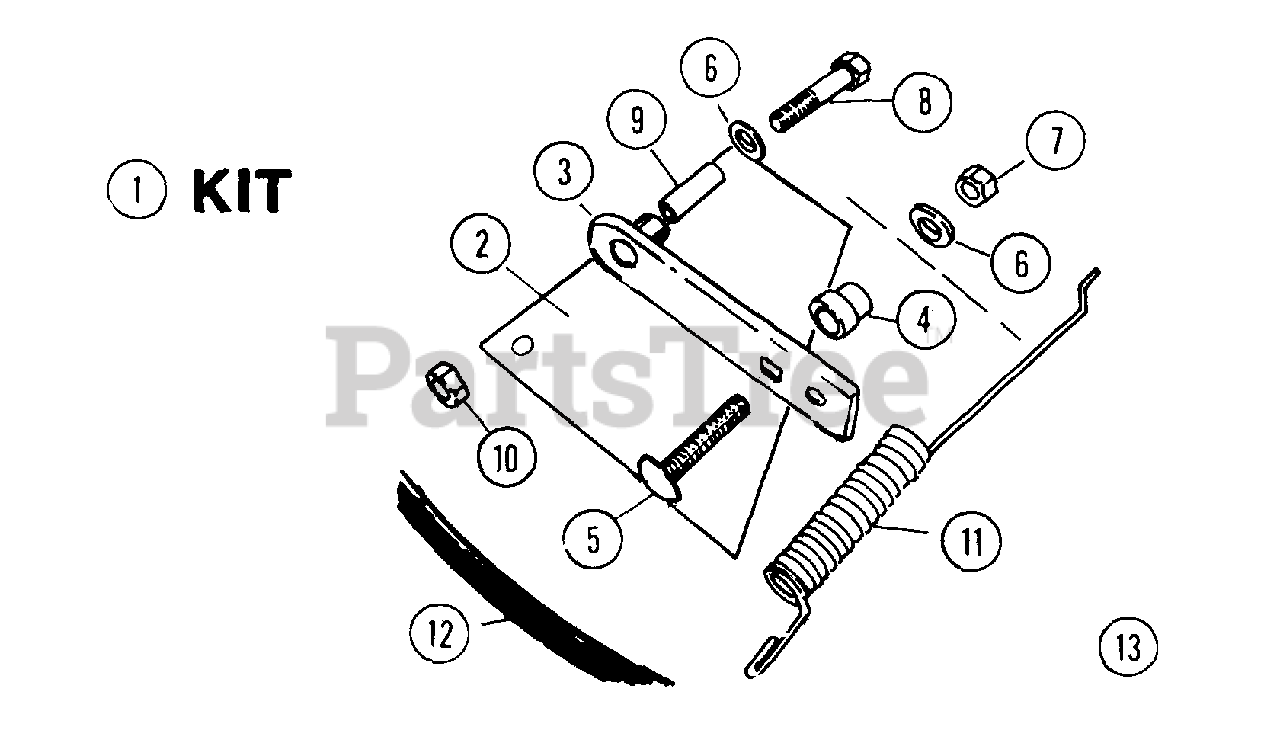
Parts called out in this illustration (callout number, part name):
1	KIT, Deck Belt Idler Spring
2	SHIELD, Adjusting Slot Cover
3	ARM, Idler
5	BOLT, 3/8Cx1-1/2 Carriage
6	WASHER, 3/8 SAE (Flat)
7	NUT, 3/8C Hex
8	CAPSCREW, 3/8Fx2 Hex Head
9	BUSHING
10	LOCKNUT, 3/8F Hex
12	BELT, Deck
13	INSTRUCTION, Kit Installation
